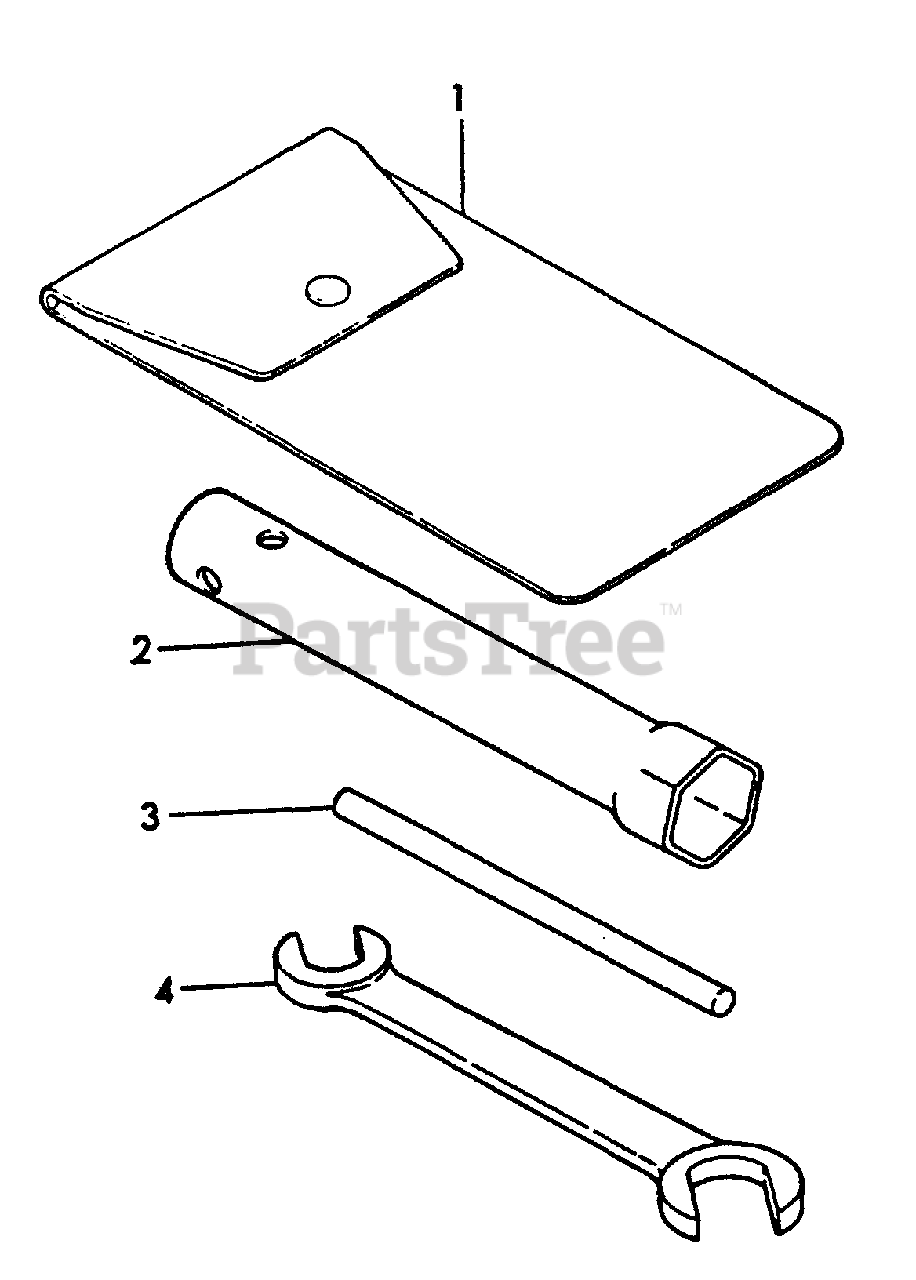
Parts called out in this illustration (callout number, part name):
1	BAG, TOOL
2	SOCKET WRENCH - 21mm
3	BAR
4	SPANNER - 10X12mm
